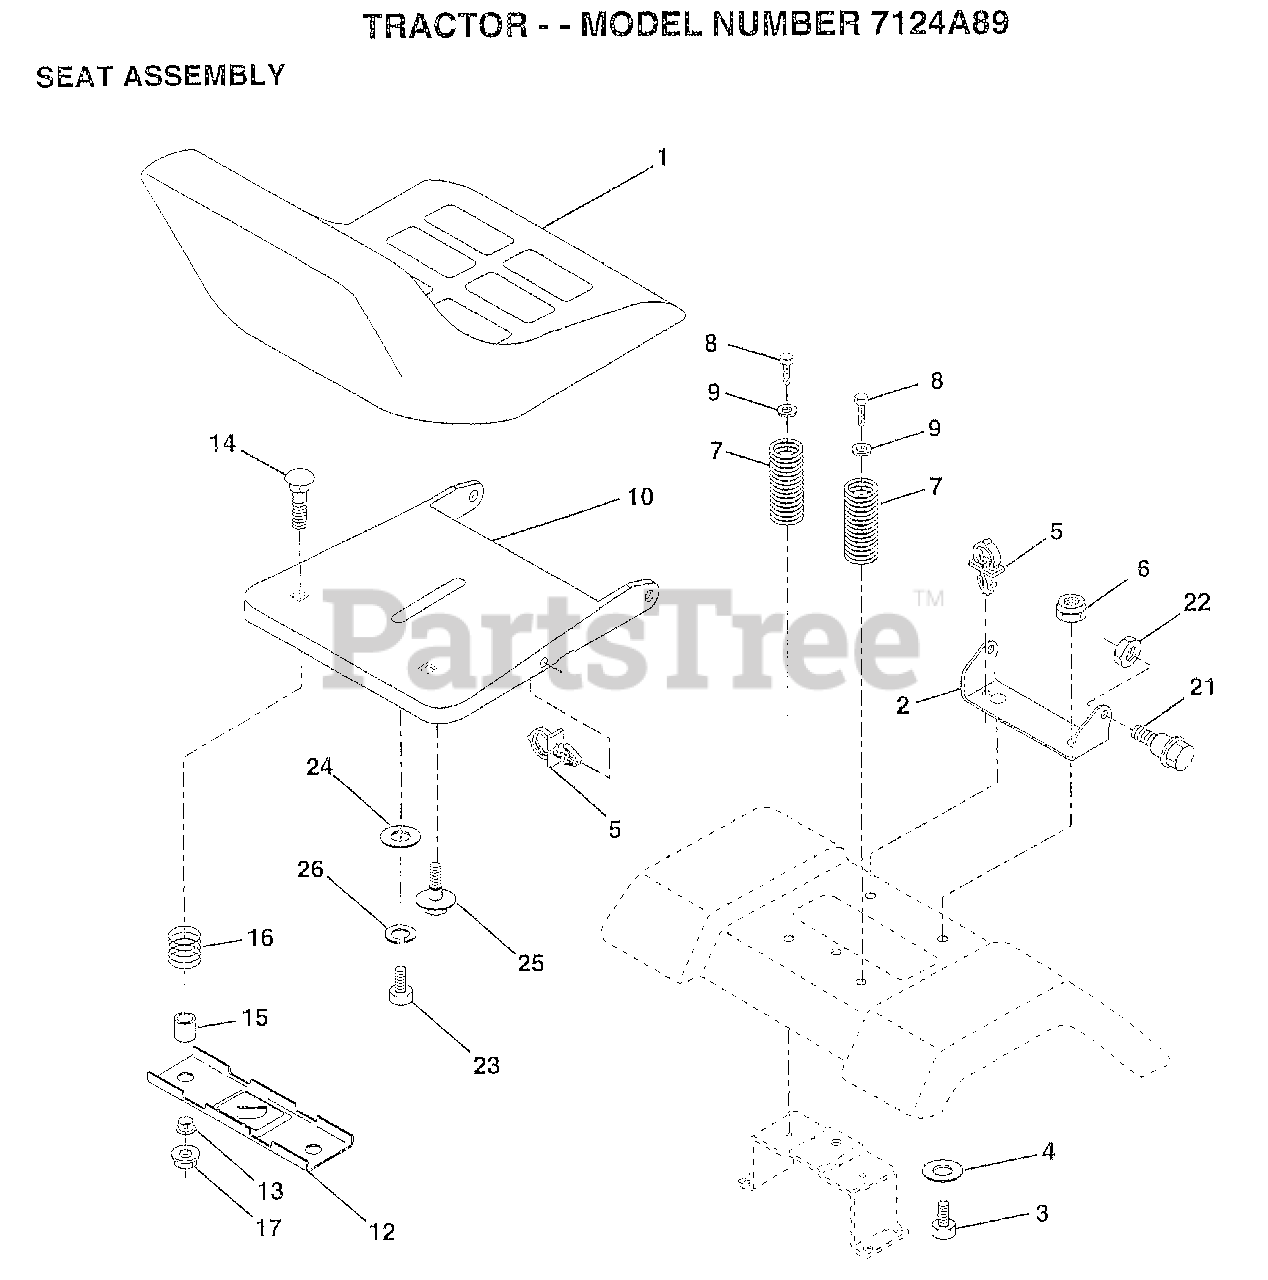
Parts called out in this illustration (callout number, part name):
2	BRACKET PVT SEAT
3	BOLT
4	WASHER PM
5	CLIP.PUSH-IN.HING
6	NUT
7	SPRING COMPRESSIO
8	SCREW GTV
9	WASHER
10	PAN-SEAT
12	BRKT SWITCH
13	BUSHING
14	BOLT-RD HD SQ NK
15	SPLIT SPACER
16	SPRING
21	"BOLT,SHOULDER"
22	NUT
23	BOLT
24	WASHER
25	"BOLT,SHOULDER"
26	LOCKWASHER
